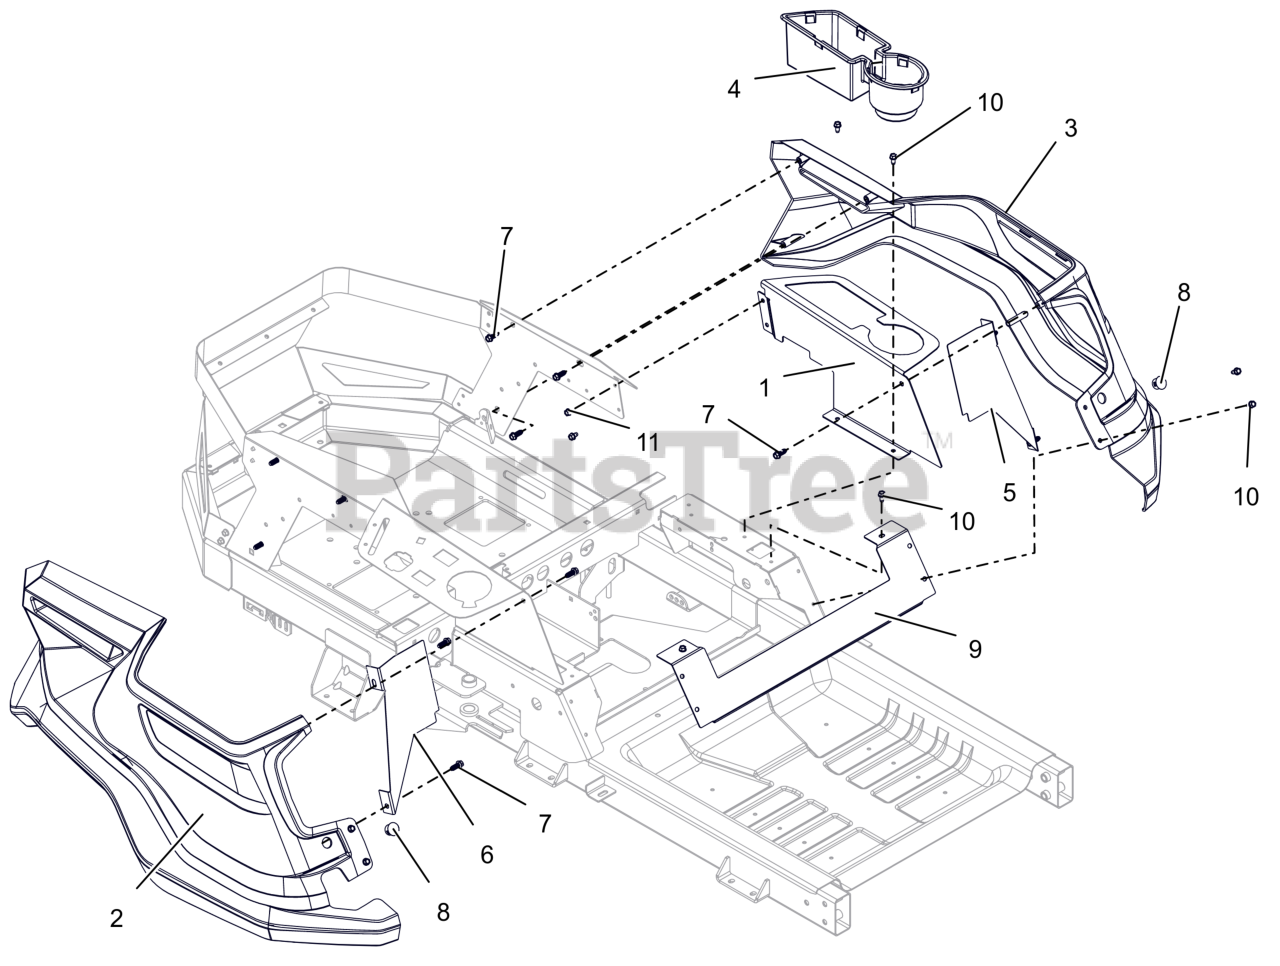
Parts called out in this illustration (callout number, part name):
1	PANEL, LEFT SIDE FENDER MOUNT
2	FENDER, RH IKON
3	FENDER, LH IKON
4	INSERT, CUP/STORAGE HOLDER
5	PLATE, LH BLOCKER
6	PLATE, RH BLOCKER
7	SCR-.312X.75 #14H H/W/H H/L CZ
8	PLUG, HOLE .75 (BLACK)
9	PLATE, SEAT KICK
10	SCR-TAP .25-20X.50 HWH ZCC
11	SCR,TAP .25-20X.375 HWH TR ZCC
